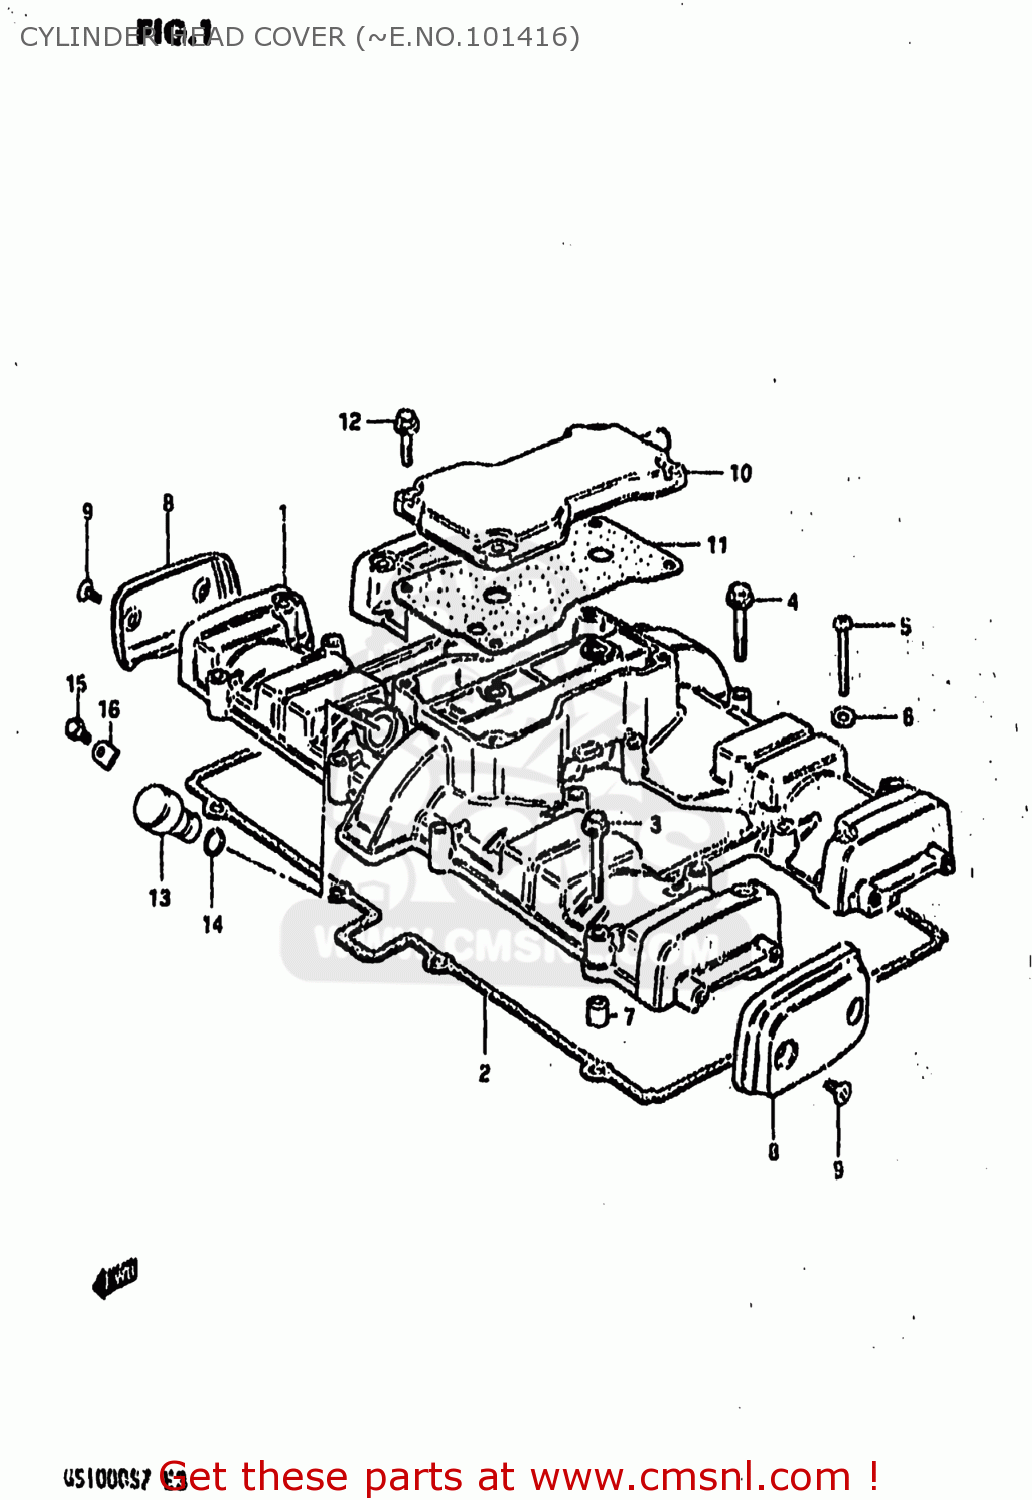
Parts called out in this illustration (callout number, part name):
1	COVER,CYLINDER HEAD
2	GASKET,CYLINDER HEAD COVER (MCA)
3	BOLT
4	BOLT 6X35
5	SCREW 6X40
6	GASKET (NAS)
7	PIN(6.2X8X11)
8	CAP,CYLINDER HEAD COVER
9	SCREW(5X12)
10	COVER,BREATHER
11	GASKET (MCA)
12	BOLT,REAR
13	PLUG,TACH GEAR SLEEVE HOLE
14	SEAL,TACHOMETER DRIVEN
15	SCREW(5X12)
16	PLATE,TACH DRIVE GEAR SLEEVE
